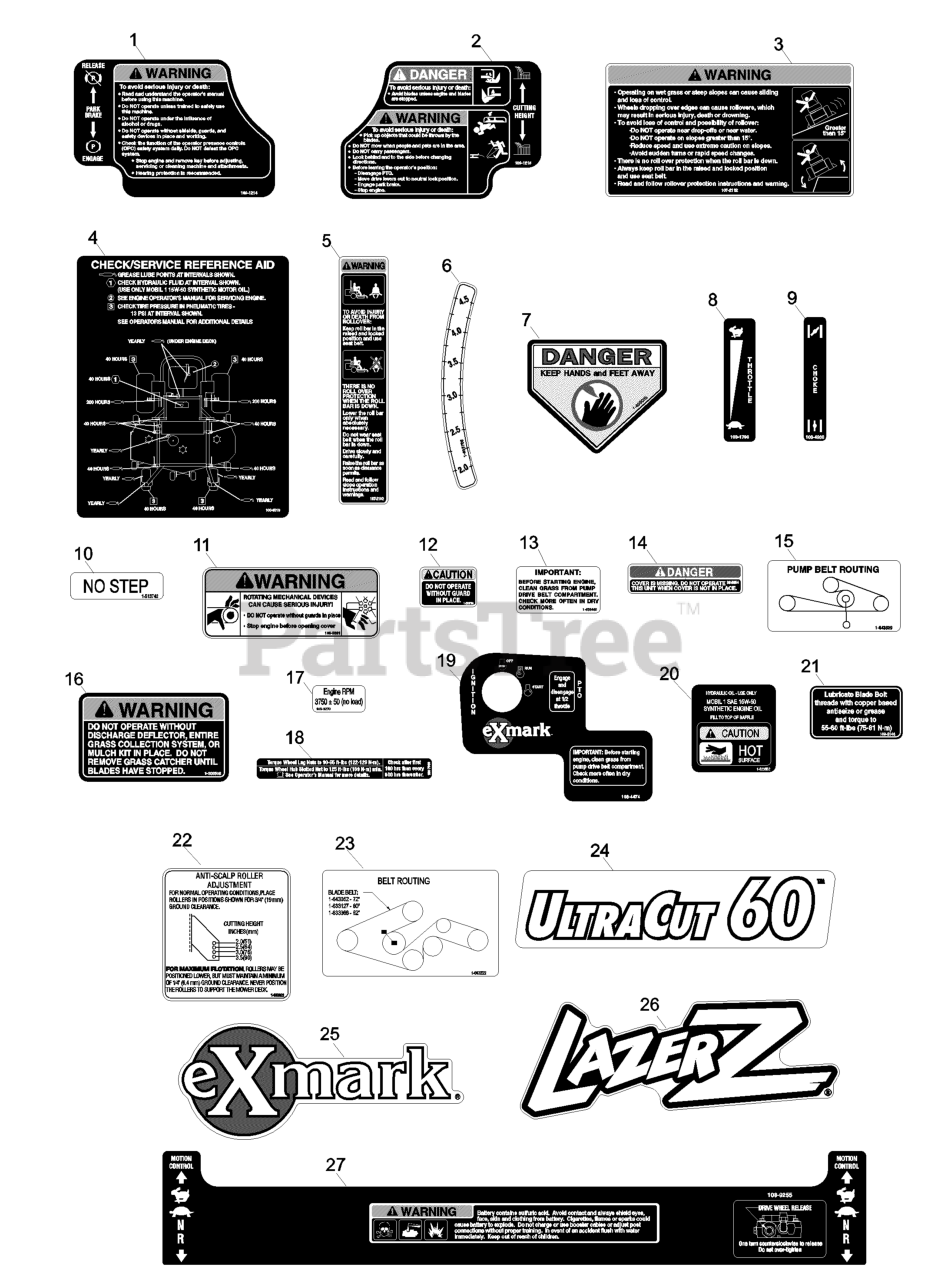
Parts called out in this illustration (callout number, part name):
1	DECAL,PARK BRAKE
2	DECAL,DECK HEIGHT
3	DECAL-WARNING
4	DECAL,CHECK SERVICE LZ
5	DECAL-WARNING, FOLDING RO
6	DECAL-HEIGHT, DECK
7	DECAL-DANGER
8	DECAL,THROTTLE ONLY
9	DECAL,CHOKE
10	DECAL,NO STEP
11	DECAL-DEVICES, ROTATING
12	DECAL-GUARD
13	DECAL-IMPORTANT
14	DECAL-COVER, MISSING
15	DECAL-ROUTING, BELT
16	DECAL-WARNING, DISCHARGE
19	DECAL,IGNITION/PTO
21	DECAL,BOLT TORQUE
22	Decal, Antiscalp
23	DECAL,BELT ROUTING
24	DECAL,ULTRACUT 60
25	DECAL,EXMARK
26	DECAL,LAZER MODEL
27	DECAL, TOP CONSOLE LZ
